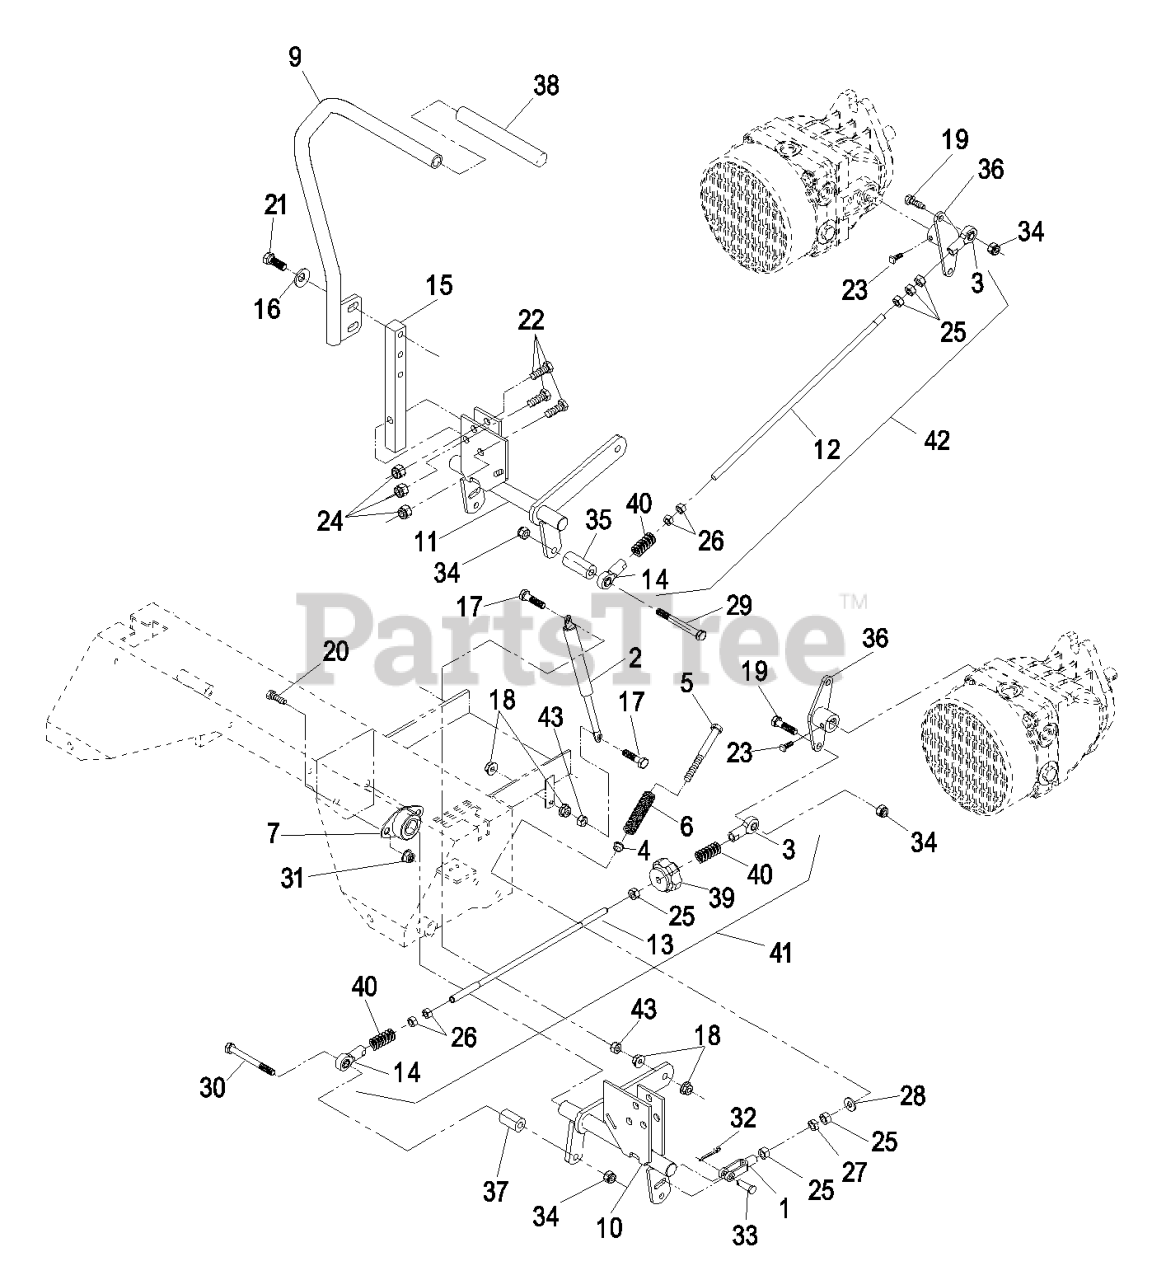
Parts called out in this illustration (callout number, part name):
1	YOKE-ADJUSTABLE
3	BALLJOINT-RH
4	BUSHING-FLANGED
5	BOLT-RETURN, NEUTRAL
6	SPRING-RETURN, NEUTRAL
7	BEARING-FLANGE, SIDE
9	ASM.RH LEVER/GRIP
12	LINK,XP HYDRO CONNECT RH
13	LINK,TRACKING ROD XP
14	BALLJOINT-LH
15	ARM-SHAFT, CONTROL
16	WASHER-BELLEVILLE
17	SCREW-HH
19	SCREW-HH
20	SCREW-HH
21	SCREW-HH
22	SCREW-HH
23	SCREW-SET
24	NUT-LOCK, NI
25	NUT-HEX
27	NUT-JAM
28	WASHER-FLAT
29	SCREW-HH
30	SCREW-HH
31	NUT-HHF, WHIZ
32	PIN-COTTER
33	PIN-CLEVIS
34	NUT-LOCK, NI
35	SPACER-CONTROL, HYD
36	ARM-CONTROL, HYDRO
37	SPACER-HYDRO CONTROL, LH
38	GRIP,CONTROL LEVER
39	KNOB-TRACKING
40	SPRING-COMPRESSION
41	TRACKING ROD ASM
42	RH HYD CONNECT LINK ASM
43	NUT-HEX
